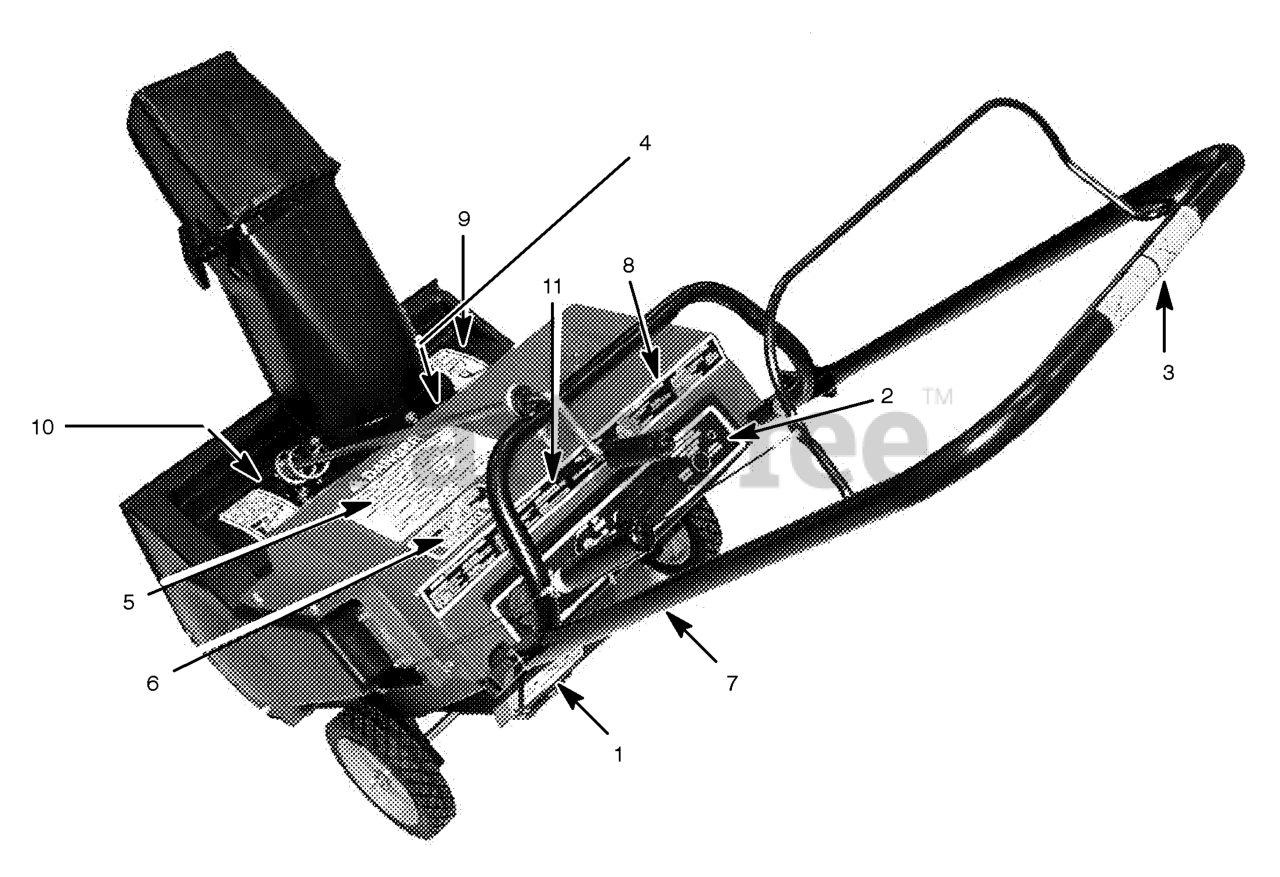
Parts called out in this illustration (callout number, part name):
1	DECAL, OFF-CHOKE-ON
2	DECAL, DANGER FOOT
3	DECAL, AUGER CONTROL
4	DECAL, CRAFTSMAN 3/20
5	DECAL, READ
6	DECAL, MUFFLER HOT
7	DECAL, EPA 3HP MASS
8	DECAL, ENGINE STARTING INSTRUCTIONS
9	DECAL, DANGER CHUTE HAND
10	DECAL, DANGER AUGER FOOT
11	DECAL, FUEL MIX SNOW
